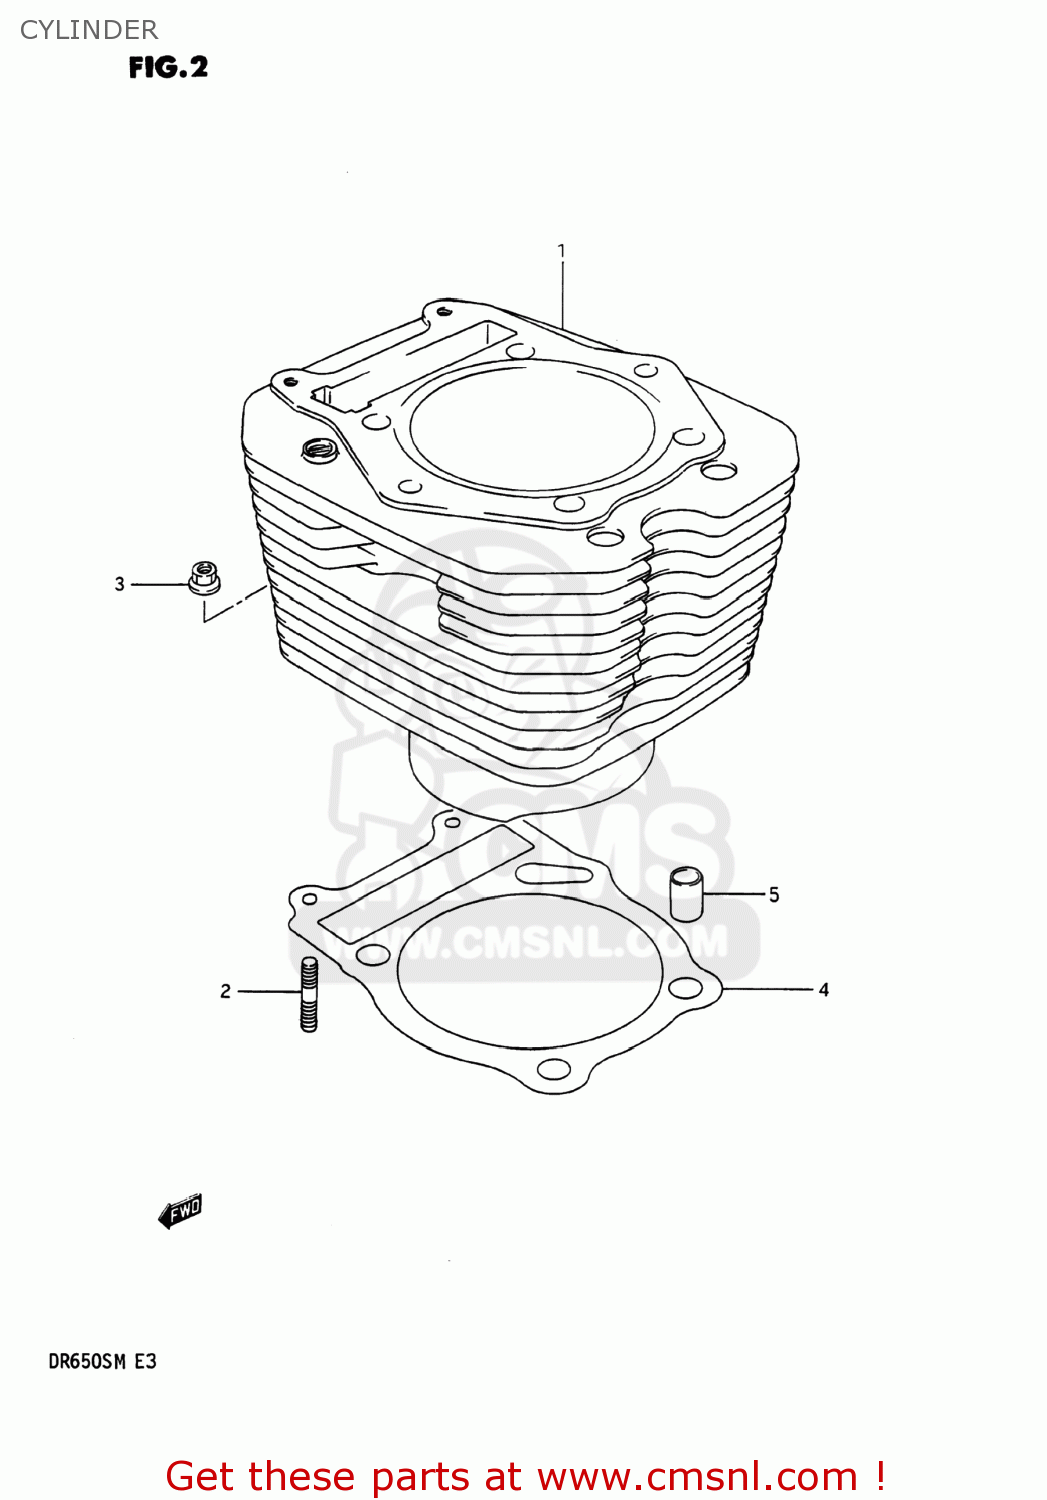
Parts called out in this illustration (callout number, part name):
1	CYLINDER
2	STUD BOLT L:20
3	NUT 6MM
4	GASKET,CYLINDER (NAS)
5	PIN
